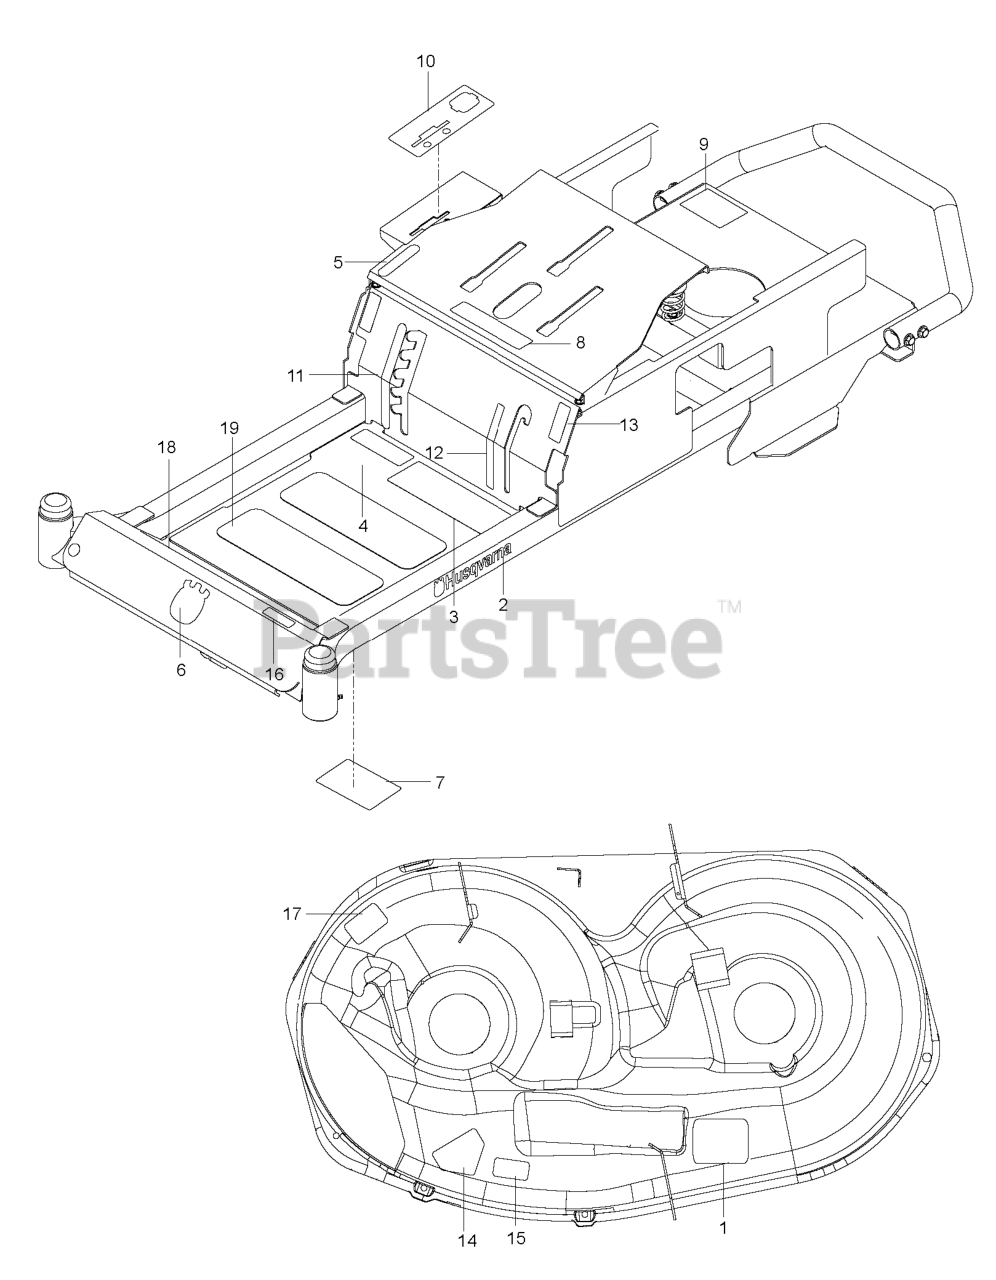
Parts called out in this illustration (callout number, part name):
1	DECAL, BELT ROUTING
2	RP.DECAL.BADGE.170MM.TEXTLOGO
3	DECAL, SAFETY WARNING
4	DECAL, SOUND POWER, 100DB
5	DECAL, PARK BRAKE
6	DECAL.AUGER.HUSQ.CROWN.SNOW
7	DECAL, SERVICE
8	EURO DECAL-BATTERY WARNIN6
9	DECAL, DO NOT TOW
10	DECAL, CONTROL PANEL HUS
11	DECAL, DECK HEIGHT
12	DECAL, BLADE ENGAGEMENT
13	DECAL, MOTION CONTROL
14	DECAL, CPSC
15	DECAL, EURO SEVERING
16	DECAL, RZ19
17	DECAL.DECK.6MIL./DEF.SHLD.WARN
19	ANTI-SKID PAD
